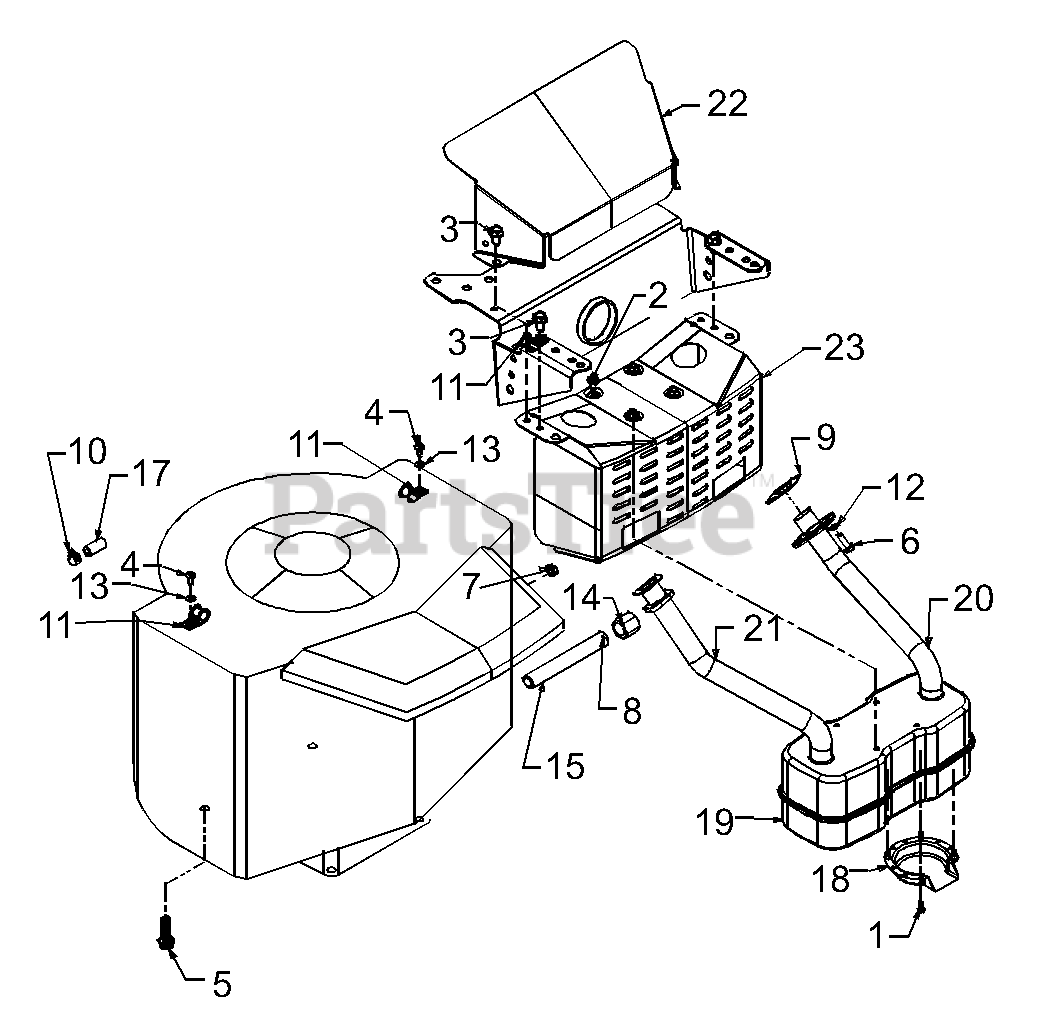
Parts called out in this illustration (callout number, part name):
1	Hex Tap Scr. #8-32 x .38" Lg.
2	Hex Wash. TT-Tap Scr. 1/4-20 x 5" Lg.
3	Hex Wash. TT-Tap Scr. 5/16-18 x .62"
4	Truss Mach. Scr. #10 x .5" Lg.
5	Hex Hd. Tap Scr. 3/8-16 x 1.25" Lg.
6	Hex Bolt 1/4-20 x .75"Lg.
7	Hex Sems Nut 1/4-20 Thd.
9	Exhaust Gasket
10	Hose Clamp
11	Clamp
12	Lock Washer 1/4" I.D.
13	Flat Washer .188" I.D. x .438" O.D.
14	Oil Drain Cap
15	Pipe Nipple 3/8 x 18 NPT.
17	Fuel Line 26" Lg.
18	Deflector: Muffler
19	Muffler
20	Exhaust Pipe-LH
21	Exhaust Pipe-RH
